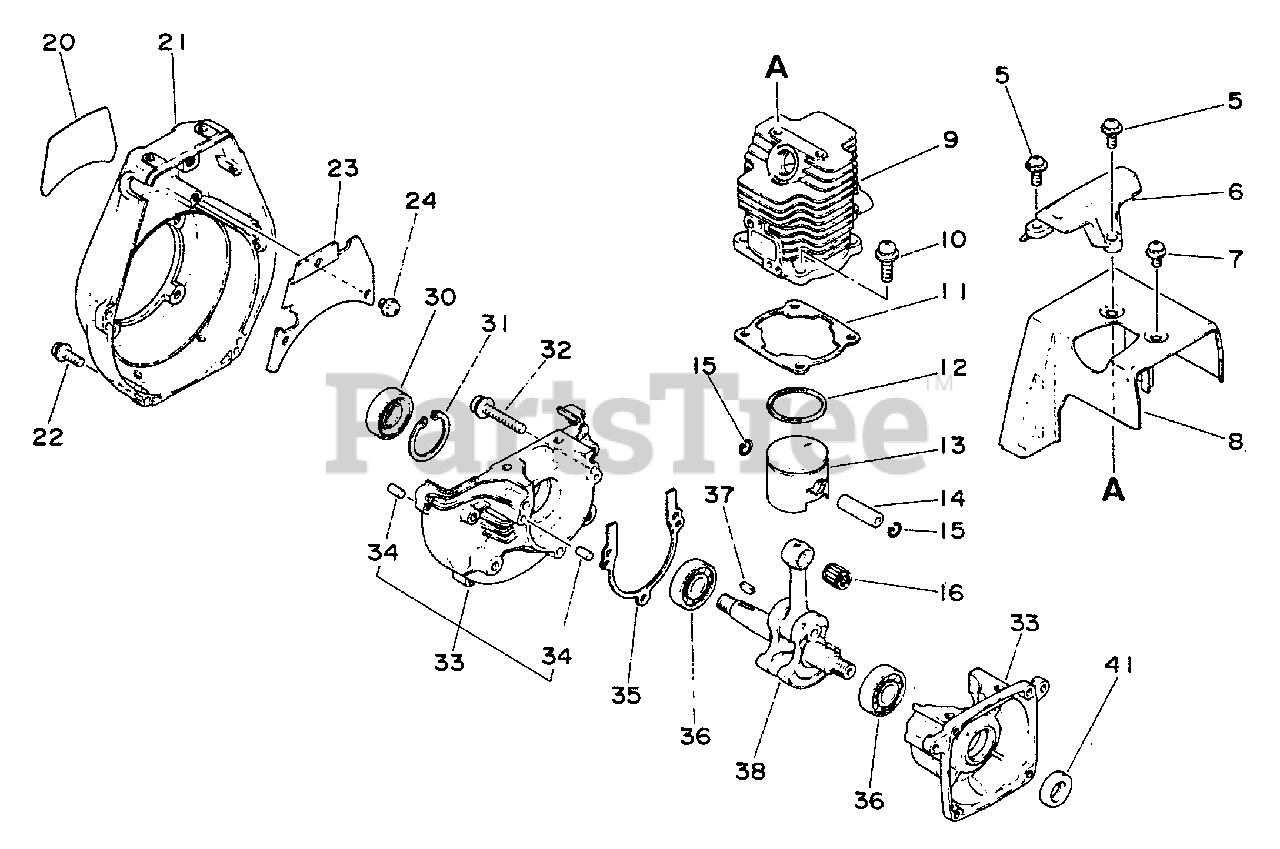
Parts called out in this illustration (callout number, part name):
5	SCREW 4×14
6	GUARD, TOP
7	SCREW 4×10
8	COVER, ENGINE
9	CYLINDER
10	SCREW 5×16
11	GASKET, CYLINDER
12	RING, PISTON
13	PISTON
14	PIN, PISTON
15	RING, SNAP
16	BEARING, NEEDLE
20	LABEL, MODEL
21	COVER, FAN
22	SCREW 4×16
23	PLATE, GUIDE
24	SCREW 4×8
30	SEAL, OIL 12
31	RING, SNAP 28
32	SCREW 5×28
33	CRANKCASE KIT
34	PIN, LOCATING 4
35	GASKET, CRANKCASE
36	BEARING, BALL 6001
37	KEY, WOODRUFF
38	CRANKSHAFT ASSY
41	SEAL, OIL
